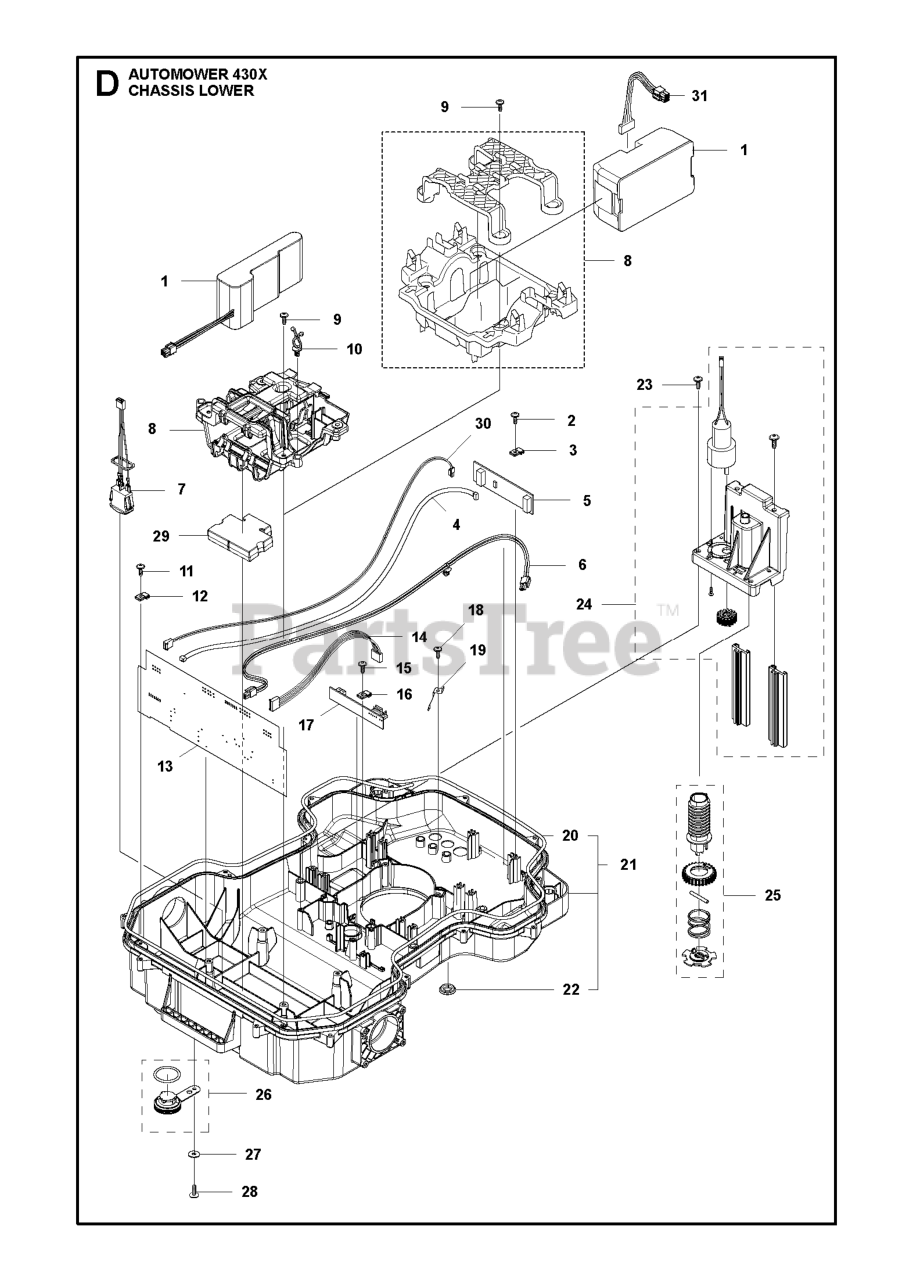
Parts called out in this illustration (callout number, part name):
1	BATTERY 588146401 PACKED
1	BATTERY
2	SCREW 14MM
3	CLAMP PCB
4	LOOM LOOP SENSOR
5	PRINTED CIRCUIT ASSY LOOP SENS
6	LOOM CHARGING LINK HIGH CHARGI
7	LOOM ON/ OFF
8	HOLDER BATTERY
9	SCREW ITXPANT
10	HOLDER TWIST LOCK
11	SCREW 14MM
12	CLAMP PCB
13	PRINTED CIRCUIT ASSY PCBA MAIN
14	LOOM HEIGHT ADJUSTMENT
15	SCREW 14MM
16	CLAMP PCB
17	PRINTED CIRCUIT ASSY PCBA CUTT
18	SCREW 14MM
19	SPRING GUIDE HEIGHT ADJUSTMENT
20	SEALING STRIP
21	CHASSIS KIT LOWER
22	GROMMET M16
23	SCREW 14MM
24	MOTOR ASSY HEIGHT MOTOR
25	SCREW KIT
26	PLUG KIT
27	WASHER
28	SCREW ITXPANT
29	WEIGHT CENTER
30	WIRING ASSY LED LIGHT EXTENSIO
